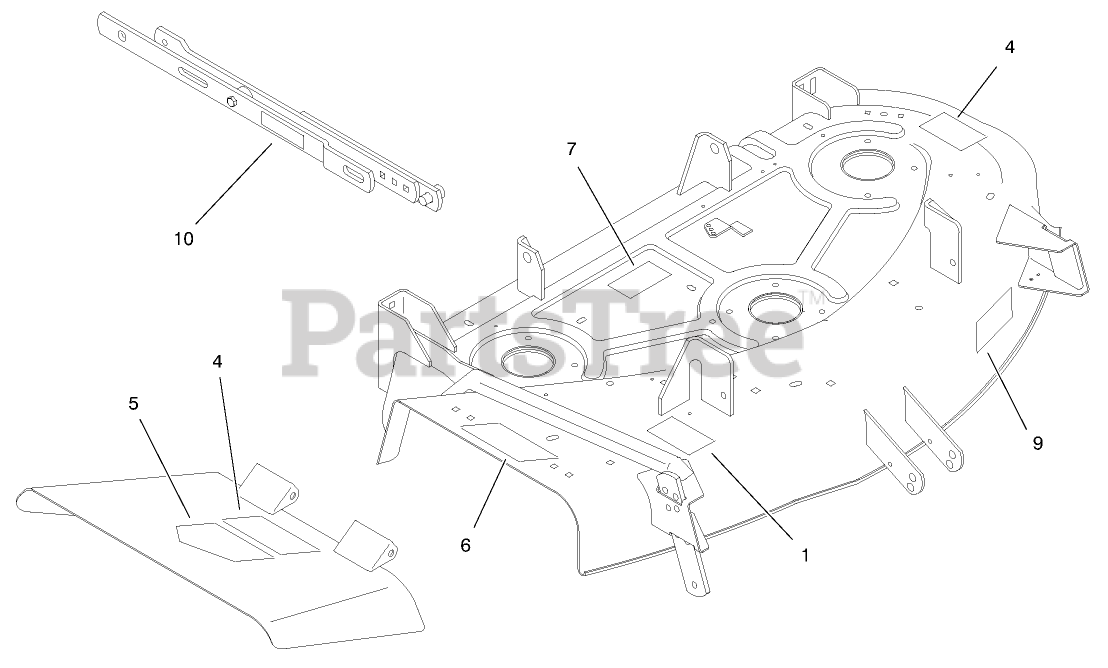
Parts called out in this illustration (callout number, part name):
1	DECAL-BELT ROUTING
4	DECAL-DANGER
5	DECAL-DANGER
6	DECAL-DANGER
7	DECAL-BELT ROUTING
9	DECAL-ADJUSTMENT, WHEEL
10	DECAL-WARNING
